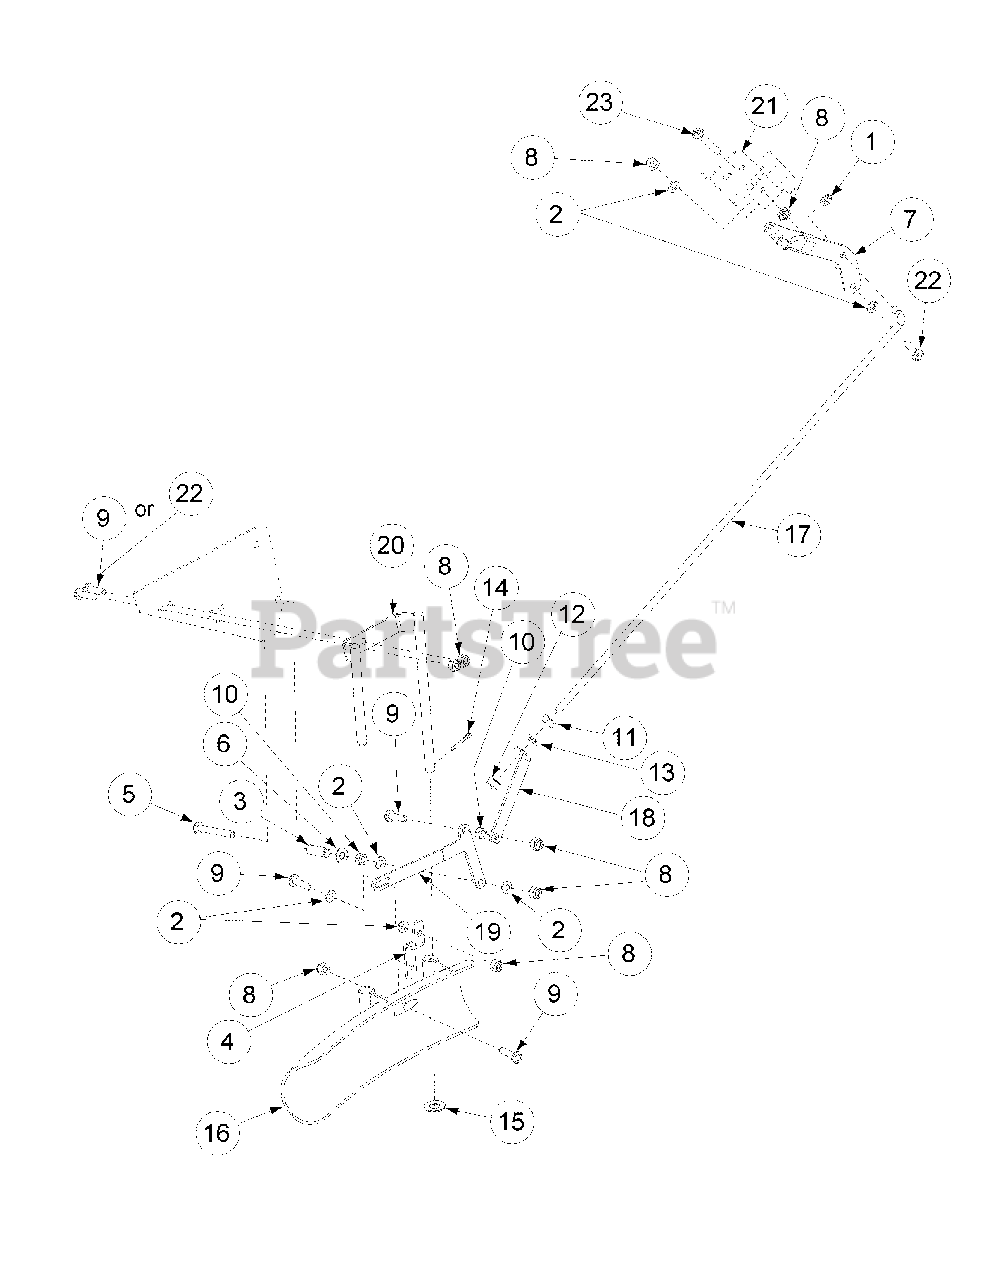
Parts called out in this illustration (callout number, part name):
1	Retainer "C" Clip
2	Nylon Washer, 1/4
3	Deflector Arm Mount Spacer
4	Offset Bracket Deflector
5	Machine Screw, 1/4-20x2
6	Flat Washer, 1/4"
7	Operating Lever and Rubber
8	Lock Nut, Nylon Insert, 1/4
9	Machine Screw Pan Head, 1/4-20x7/8
10	Hex Nut, 1/4-20
11	Hex Lock Nut, 5/16-18
12	Nut, Nylon Insert, 5/16-18
13	Lock Washer, 5/16
14	Cotter Pin, 1/8 x 1
15	Flat Washer, 3/8
16	Deflector Tube, Plastic Only
17	Deflector Actuator Rod
18	Lever Rod Deflector Bracket
19	Tube Bracket Mount, Lever, Deflector
20	Deflector Tube Mount
21	Remote Bracket
22	HHCS, 1/4-20 x .75, SS
23	Machine Screw, 1/4-20 x 1.50, SS
